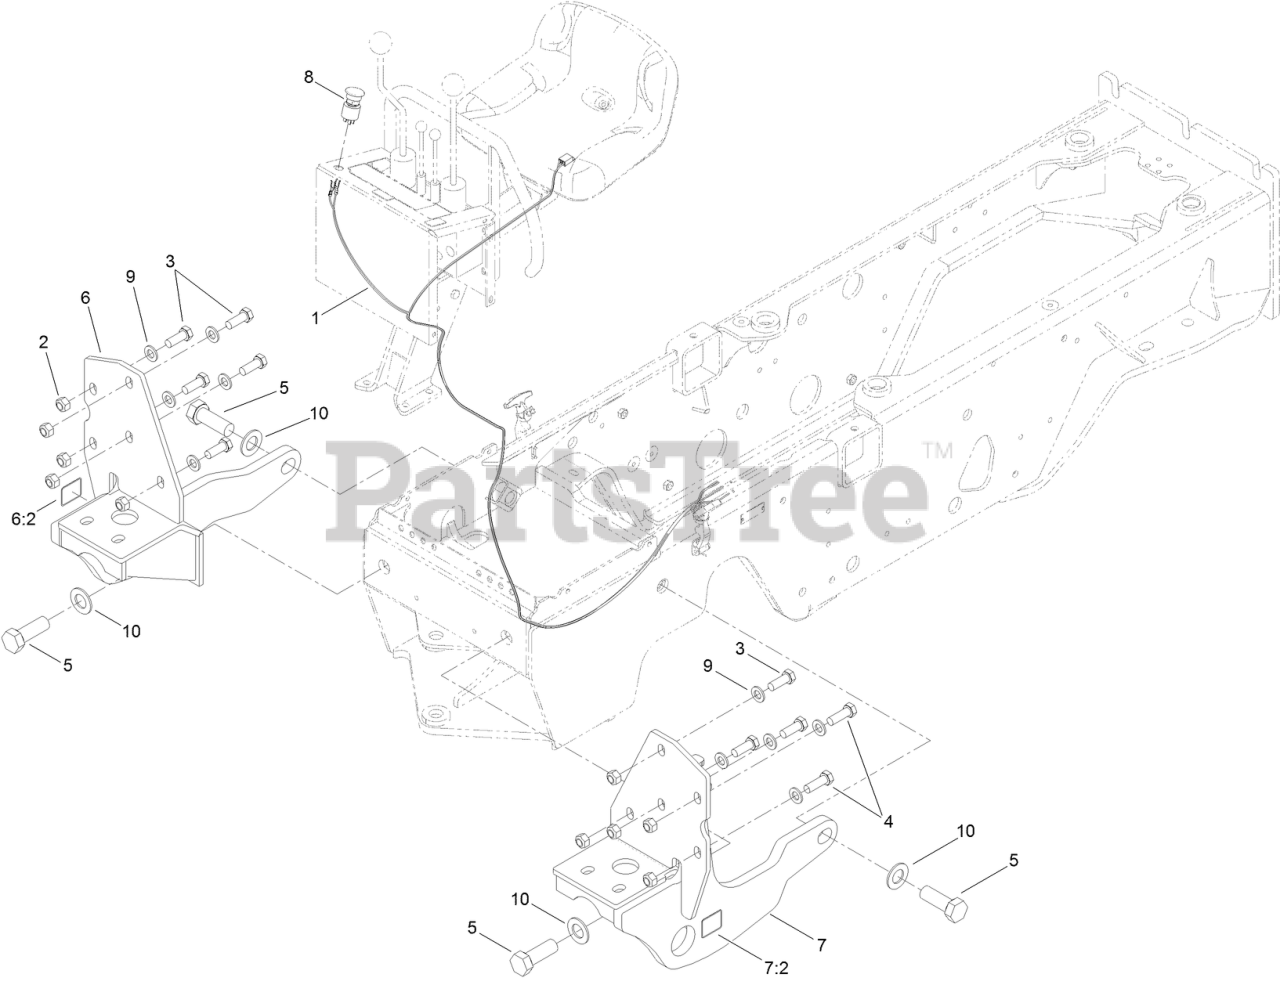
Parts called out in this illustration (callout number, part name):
1	HARNESS-WIRE
2	NUT-LOCK
4	SCREW-HH
6	RH MOUNTING BRACKET ASM
6:2	DECAL-TIE DOWN
7	LH MOUNTING BRACKET ASM
7:2	DECAL-TIE DOWN
8	BUTTON-E-STOP
9	WASHER-FLAT
